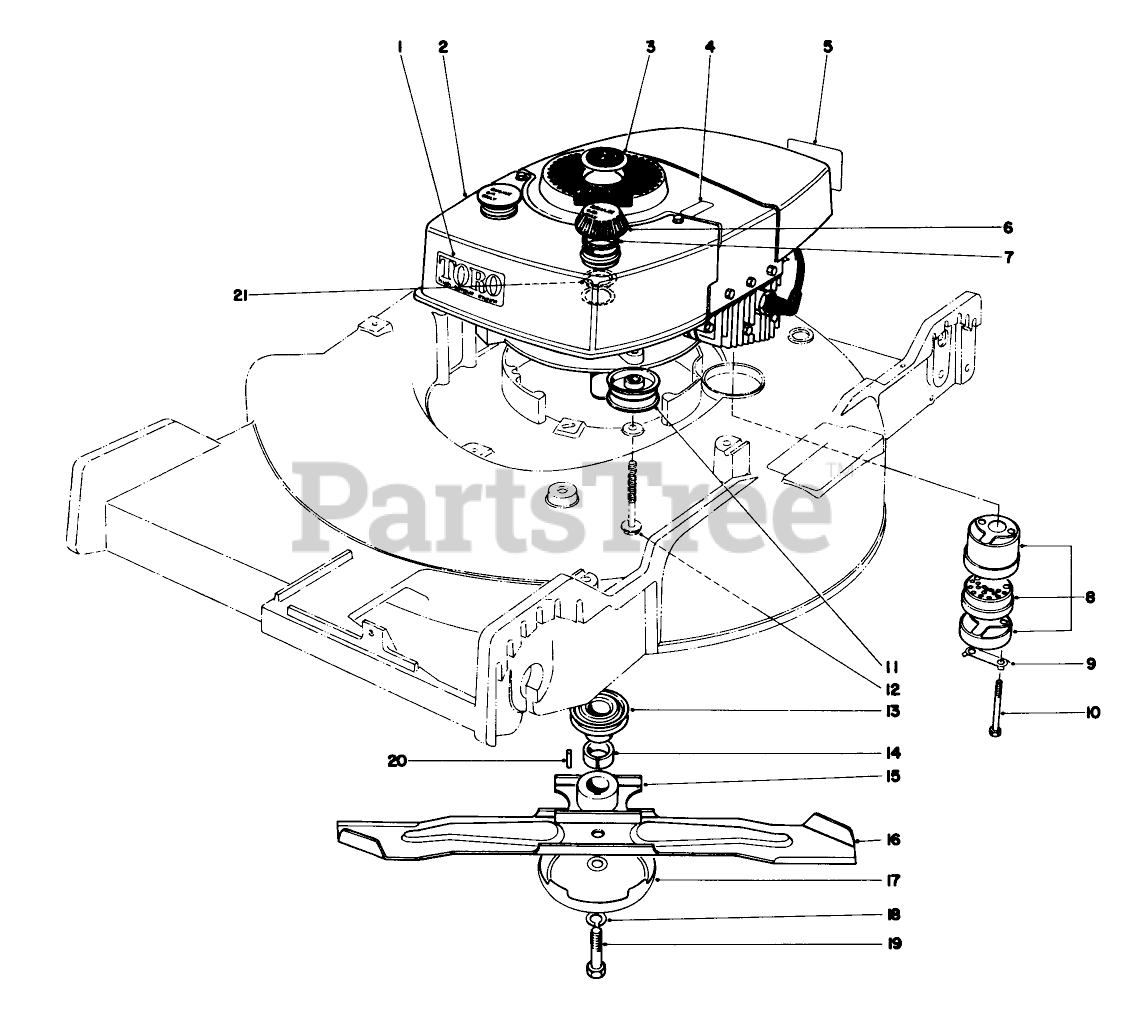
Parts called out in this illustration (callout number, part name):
2	Engine (TNT120-12003)
7	GASKET
8	MUFFLER ASM
9	CLIP - LOCKING
10	SCREW-HH
12	3/8-16 X 2-3/4 CAPSCR
15	BLADE RETAINER WA
17	Anti Scalp Cup
18	WASHER-LOCK
19	BLADE SCREW
20	KEY-SQUARE
